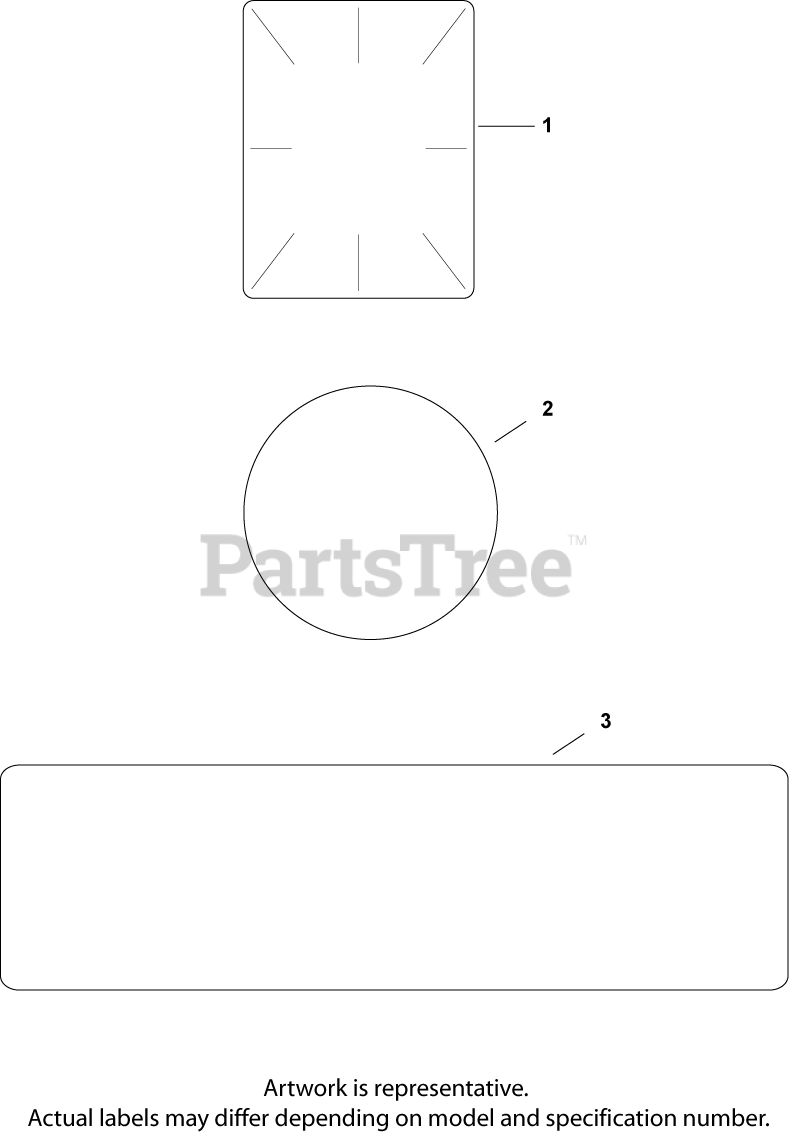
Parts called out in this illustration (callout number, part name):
1	DECAL, CLEAR LAMINATE USE 25 113 70-S
2	DECAL, GRASS SCREEN USE 24 113 499-S
3	DECAL, 25 HP - DISCONTINUED
